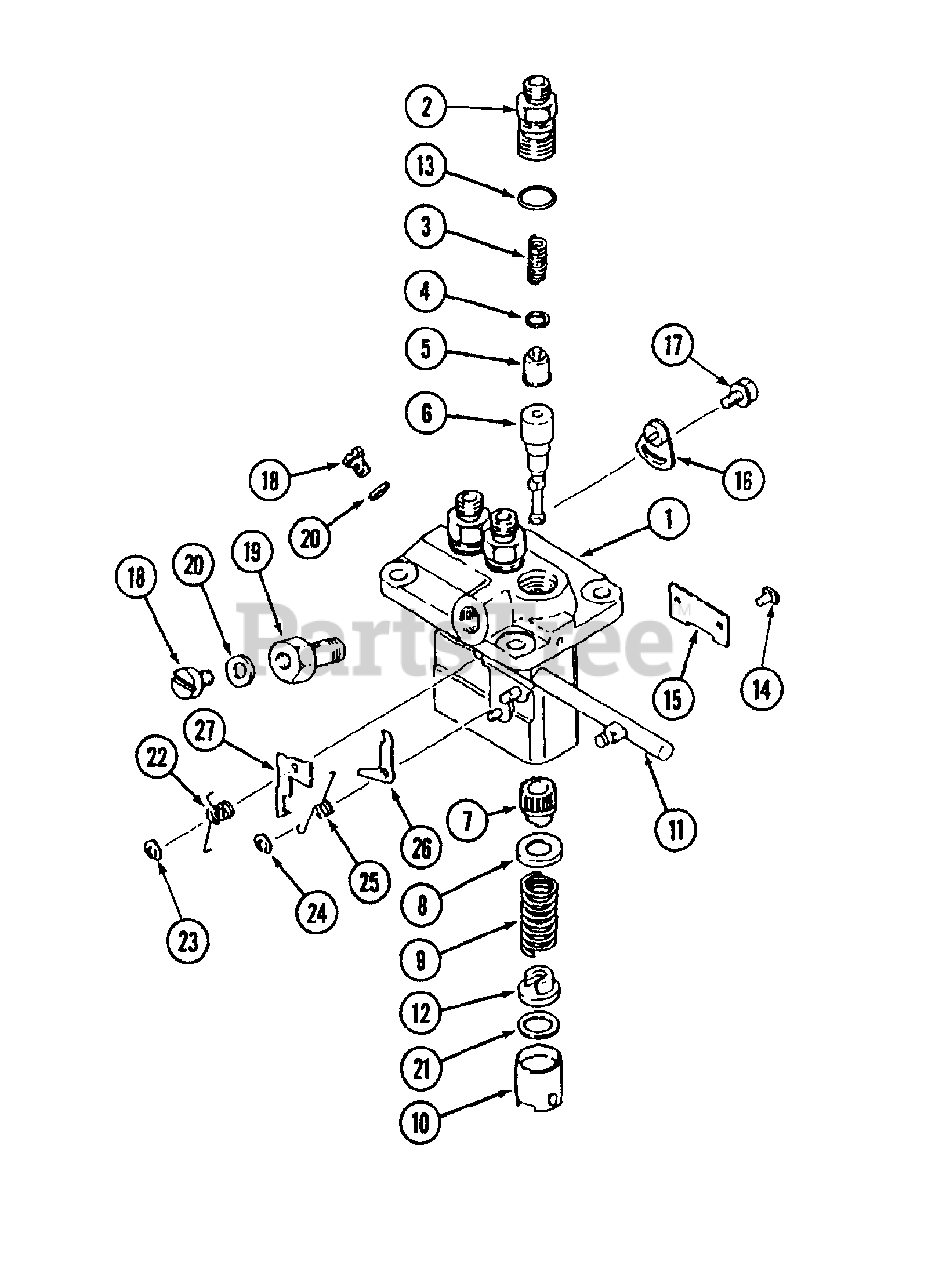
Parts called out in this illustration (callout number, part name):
1	Housing Sub Ass'y., Pump
2	Holder, Delivery Valve
3	Spring, Delivery Valve
4	Gasket, Delivery Valve
5	Valve Sub Ass'y., Delivery
6	Element Sub Ass'y., Pump
7	Sleeve, Control
8	Seat, Spring Upper
9	Spring, Pump Plunger
10	Tappet Ass'y.
11	Pack Ass'y., Control
12	Seat, Spring Lower
14	Pin, Tappet Guide
16	Plate, Adjusting
17	Bolt, Washer Head
18	Screw, Air Bleeder
19	Screw, Hollow
20	Washer, Pipe Union
21	Shim, Plate Tappet
22	Spring, Smoke Set
25	Spring, Angleich Set
26	Plate, Angleich Set
27	Plate, Smoke Set
